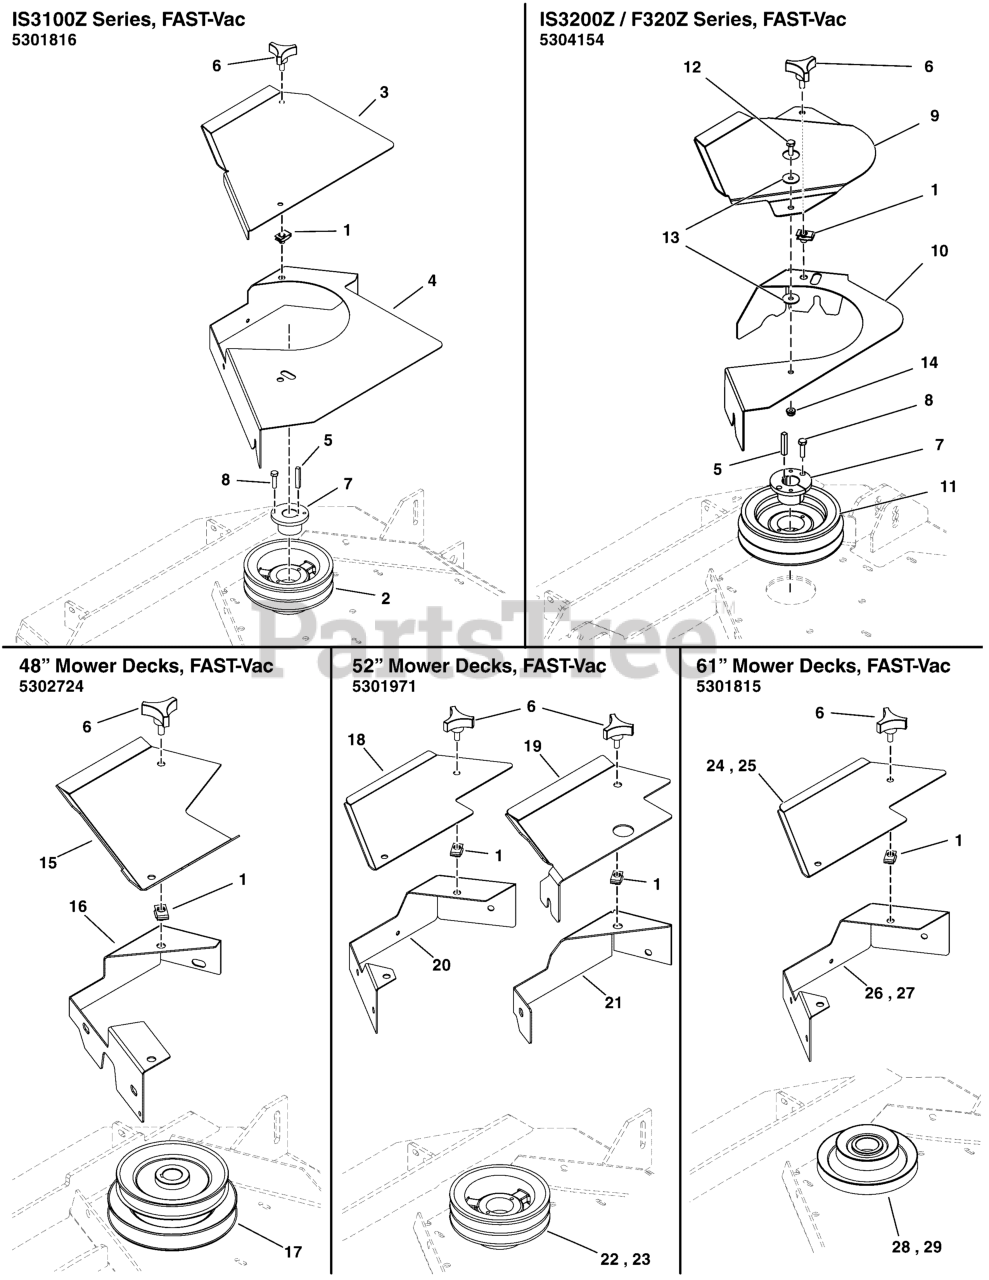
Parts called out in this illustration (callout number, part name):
1	BODY CLIP, 5/16-18-7GA MATERIAL
2	PULLEY, DOUBLE, DH4600, 5.95 OD TAPERED
3	BELT SHIELD, 61"BLOWER DECK-BK
4	WELD, GUARD 61" DECK
5	KEY 1/4 SQ X 1 1/2 LONG
6	KNOB, PLASTIC, 5/16-18 X 3/4
7	BUSHING, TAPERED HUB
8	BOLT, 1/4-20 X 1" GD5 CZ
9	SHIELD, BELT, 3200-61", BLOWER - BLK
10	GUARD, DECK PULLEY, 3200-61" - BLK
11	PULLEY, DOUBLE, 5.95/6.43 OD, IS3200
12	BOLT, 1/4-20 X 3/4 GD5 CZ
13	WASHER, 1/4 FENDER
14	NUT, 1/4-20 HEX NYLOCK FLANGE
15	GUARD, DECK - BLACK
16	GUARD, DECK 48, 52 - BLK
17	PULLEY, BLOWER 48 DECK
18	GUARD, DECK - BLACK
19	GUARD, BELT, 52/2000 SND - BLK
20	GUARD, DECK - BLACK
21	GUARD, DECK, 52/2000 SND - BLK
22	PULLEY-BLOWER 52 DECK
23	PULLEY,DECK,61 BLOWER UNIT
24	GUARD, DECK, 61", 2000 FASTVAC - BLK
25	WELD, PULLEY GUARD, 800X - BLK
26	GUARD, BELT, 61", 2000 FASTVAC - BLK
27	SHIELD, BLOWER BELT, 800X - BLK
28	PULLEY,DECK,61 BLOWER UNIT
29	PULLEY, BLOWER 48 DECK
